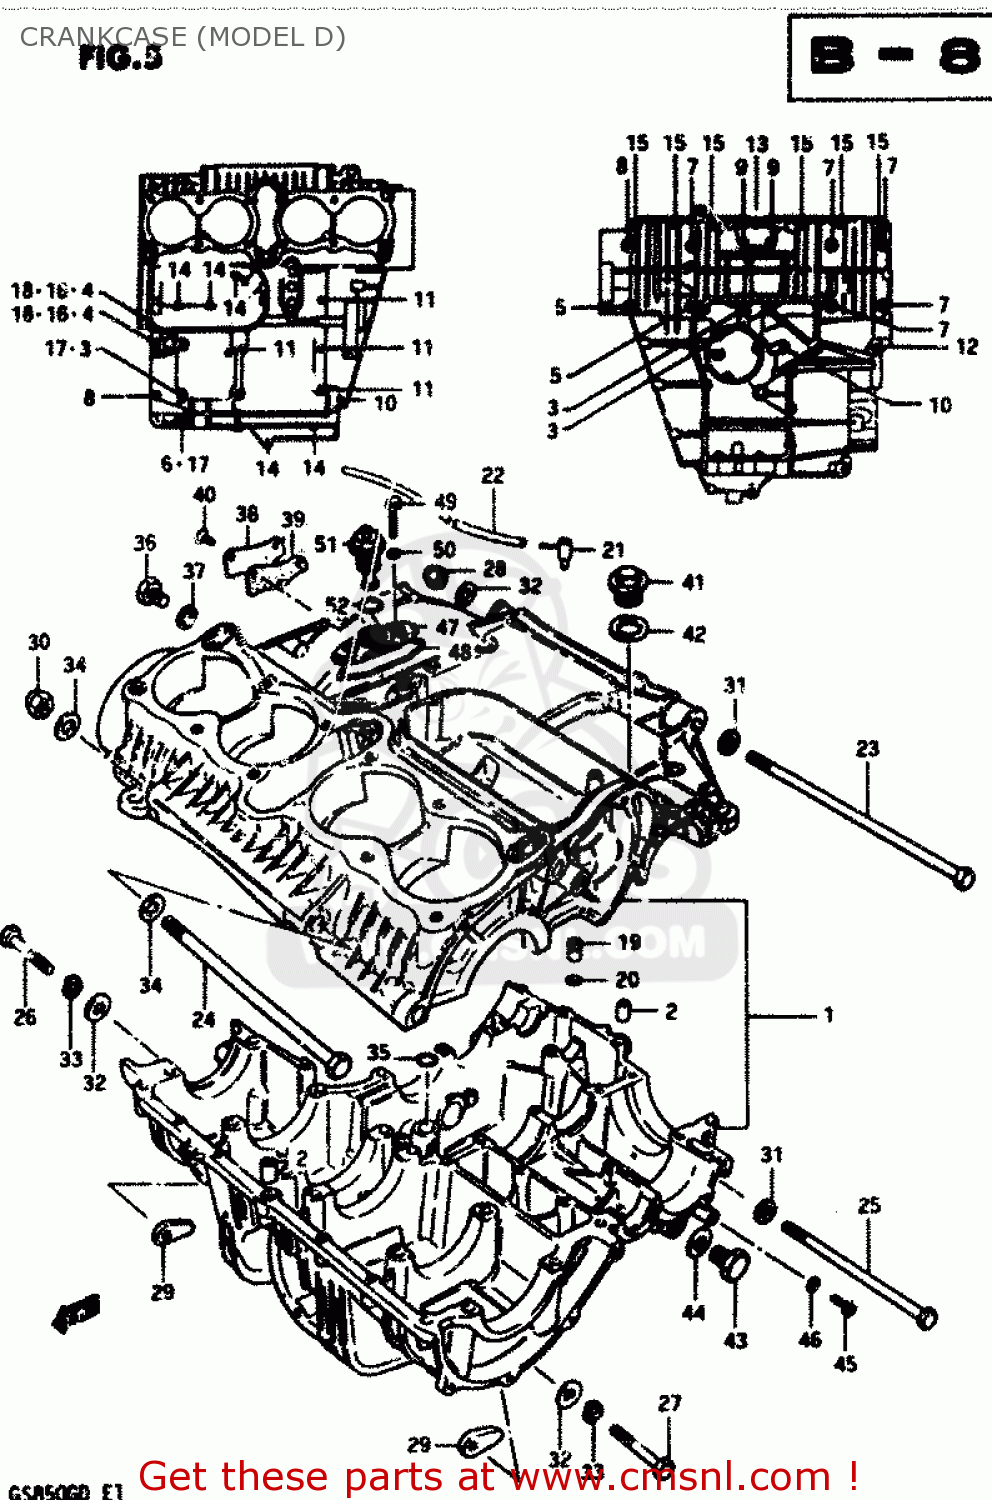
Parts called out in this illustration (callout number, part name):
1	CRANKCASE SET
2	PIN
3	BOLT
4	BOLT 8X110
5	BOLT
6	BOLT
7	BOLT (8X90)
8	BOLT (8X65)
9	BOLT 8X60
10	BOLT (6X90)
11	BOLT (6X75)
12	BOLT 6X55
13	BOLT 6X50
14	BOLT (6X45)
15	BOLT
16	NUT
17	NUT 8MM
18	GASKET 8.2X14X1 (NAS)
19	UNION
20	O RING(D:1.05,ID:3.1)
21	BPLUG,BEVEL GEAR BREATHER
22	HOSE
23	BOLT
24	SHAFT,REAR SWING ARM
25	BOLT
26	BOLT (10X60)
27	BOLT (10X50)
28	NUT (10MM)
29	NUT
30	NUT
31	WASHER (10.5X20X3.2)
32	WASHER
33	LOCK WASHER
34	WASHER
35	O RING(D:3.2,ID:12.9)
36	PLUG (14X12)
37	GASKET(14X19.2X2) (NAS)
38	CAP,OIL GALLERY
39	GASKET,OIL GALLERY (MCA)
40	SCREW
41	PLUG
42	GASKET
43	PLUG
44	GASKET(14X19.2X2) (NAS)
45	SCREW(6X10)
46	GASKET (NAS)
47	HOUSING,OIL PRESSURE SWITCH
48	O RING,PRESSURE SWITCH HOUSING
49	BOLT
50	GASKET (NAS)
51	SWITCH ASSEMBLY
52	O RING(D:1.9,ID:18.8)
